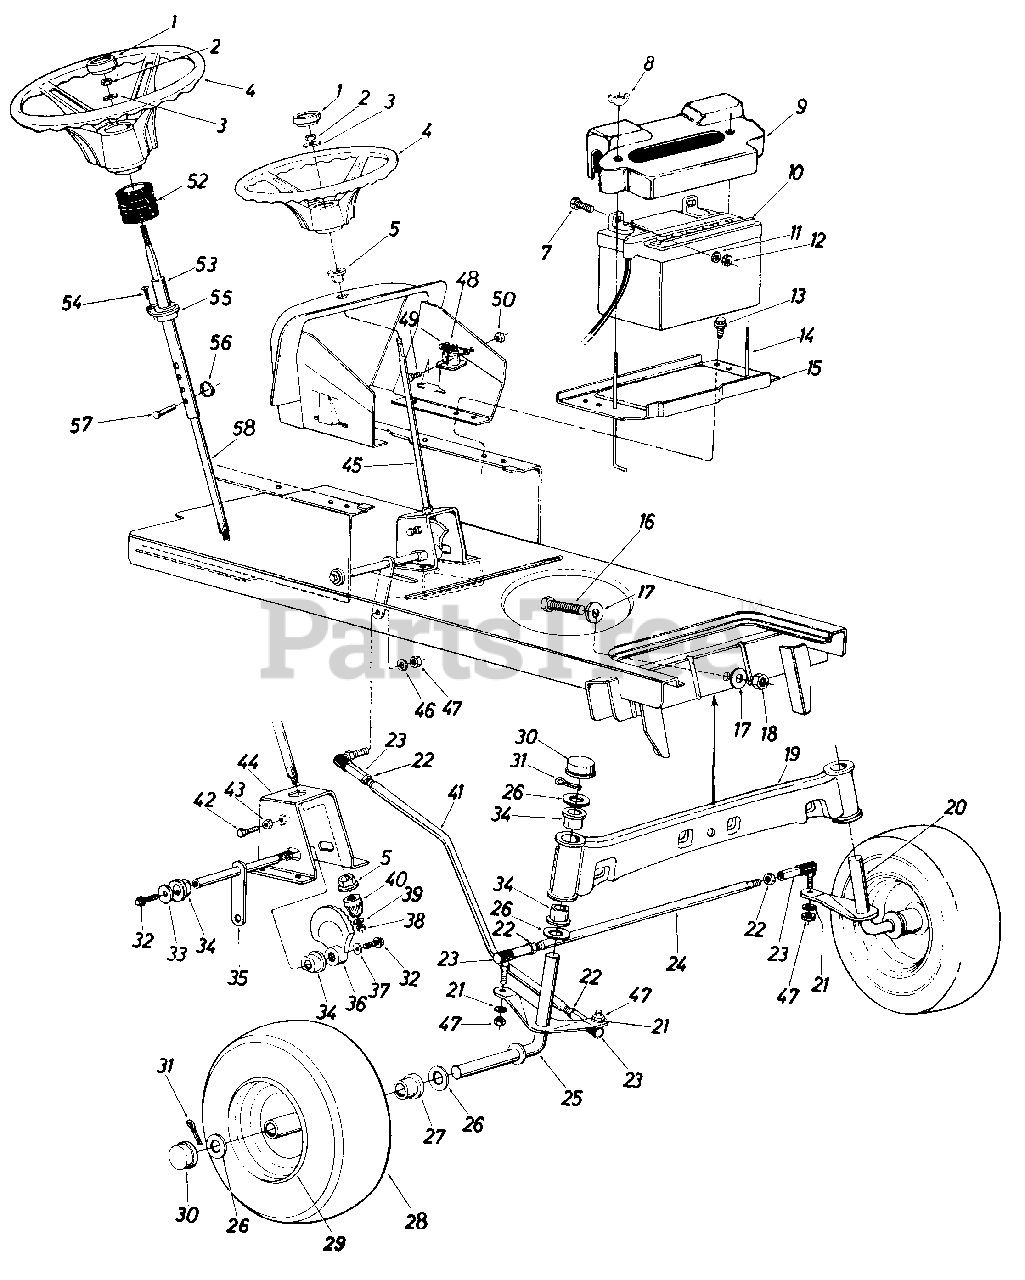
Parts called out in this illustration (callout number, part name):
1	Steering Wheel Cap
2	Hex Cent. L-Nut 5/16-18 Thd.
3	Bell-Wash. 5/16" I.D. x .87" O.D. x .060
4	Steering Wheel
5	Plastic Hex Bearing 518" I.D.
7	Hex Scr. 1/4-20 x .62" Lg.
8	Wing Nut Plastic 1/4-20 Thd.
9	Battery Cover
10	12-V Battery
11	L-Wash. 1/4" Scr.
12	Hex Nut 1/4-20 Thd.
13	Hex Thd. Rolling Scr. 1/4-20 x.50" Lg.
14	Battery Hold Down Rod
15	Battery Plate
16	Hex Scr. 5/8-18 x 2.50" Lg.
17	Flat Wash. .66" I.D. x 2.25" O.D. x .17
18	Hex Cent. L-Nut 5/8-18 Thd.
19	Front Pivot Bar Ass'y.
20	Front Axle Ass'y.-L.H.
21	L-Wash. 3/8" Scr.
22	Hex Jam Nut 3/8-24 Thd.
23	Ball Joint Ass'y.
24	Tie Rod
25	Front Axle Ass'y.-R.H.
26	Fl-Wash. .780 I.D. x 1.59 O.D.
27	Flange Bearing
28	Front Wheel Ass'y. Comp.
29	Front Wheel Rim Only
30	Dust Cover
31	Cotter Pin 5132" Dia. x 1.00" Lg.*
32	Hex Scr. 3/8-24 x .75" Lg. Grade 5
33	Fl-Wash. 3/8 I.D. x 1.25 O.D. x .090
34	Flange Double "D" Brg. .753 I .D.
35	Steering Arm Shaft Ass'y.
36	Side Gear-Steering
37	Bell-Wash. 3/8" I.D.
38	Hex Cent. L-Nut 5/16-24 Thd.
39	Fl-Wash. 5/16" I.D. x .62 O.D. x .059
40	Pinion Gear-Steering
41	Drag Link
42	Hex Nylon Scr. 3/8-16 x 1.25" Lg.
43	Hex Nut 3/8-16 Thd.*
44	Steering Gear Sup. Ass'y.
45	Steering Shaft
46	L-Wash. 3/8" Scr.*
47	Hex Nut 3/8-24 Thd.*
48	Solenoid
49	Hex Bolt 1/4-20 x .50" Lg.*
50	Hex Sems Nut 1/4-20 Thd.
52	Steering Bellow
53	Upper Steering Shaft
54	Oval Hd. Cr.-Sunk Scr. #10 x 518" Lg.
55	Fl-Bearing .89" I.D. x 1.36" O.D.
56	Hex L-Nut 1/4-20 Thd.
57	Hex Bolt 1/4-20 x 1.31" Lg.
58	Lower Steering Shaft
